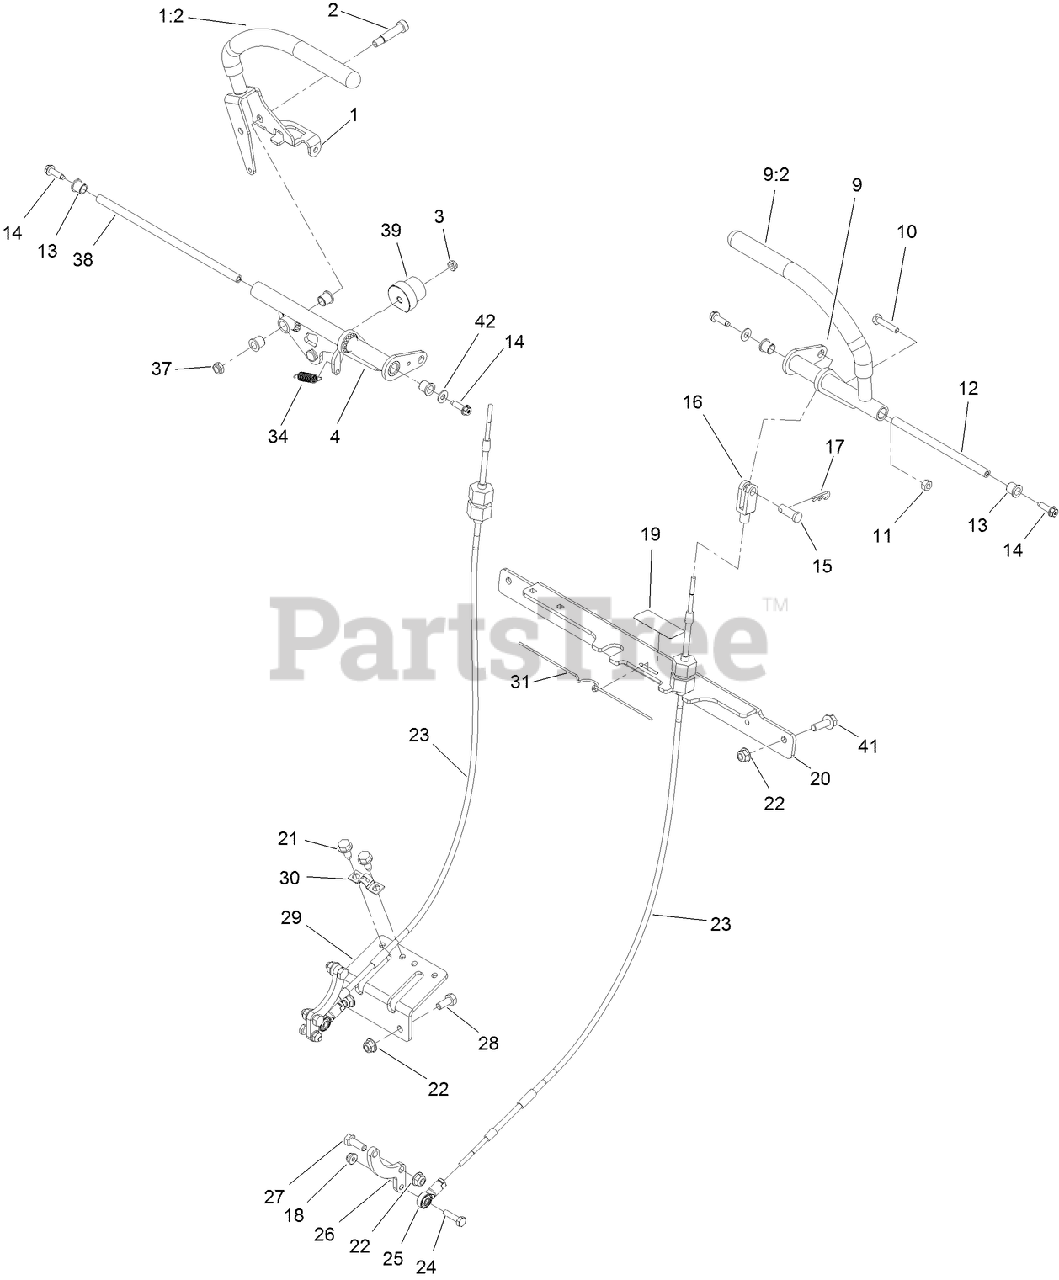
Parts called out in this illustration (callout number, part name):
1	RH LEVER ASM
2	SCREW-HSH
3	NUT-LOCK, NI
4	RH MOTION CONTROL ASM
9	LH MOTION CONTROL ASM
10	SCREW-HH
11	NUT-HEX
12	SHAFT-PIVOT, MOTION CONTROL
13	BEARING
14	SCREW-HH, TORX
15	PIN-CLEVIS
16	YOKE-FEMALE
18	NUT-HF
19	DECAL-TRACKING, HYDRO
20	BRACKET-CROSS
21	SCREW-HWHTF
22	NUT-HF, NI
23	CABLE ASM
24	SCREW-HH
25	ROD END-BALL JOINT
26	ARM-CONTROL, PUMP
27	SCREW-HH
28	SCREW-HH
29	BRACKET-CLAMP, CABLE
30	CLAMP-CABLE
31	CLIP-SPRING
34	SPRING-EXTENSION
37	NUT-LOCK, NI
38	SHAFT-PIVOT
41	SCREW-HHF
42	WASHER-FLAT
